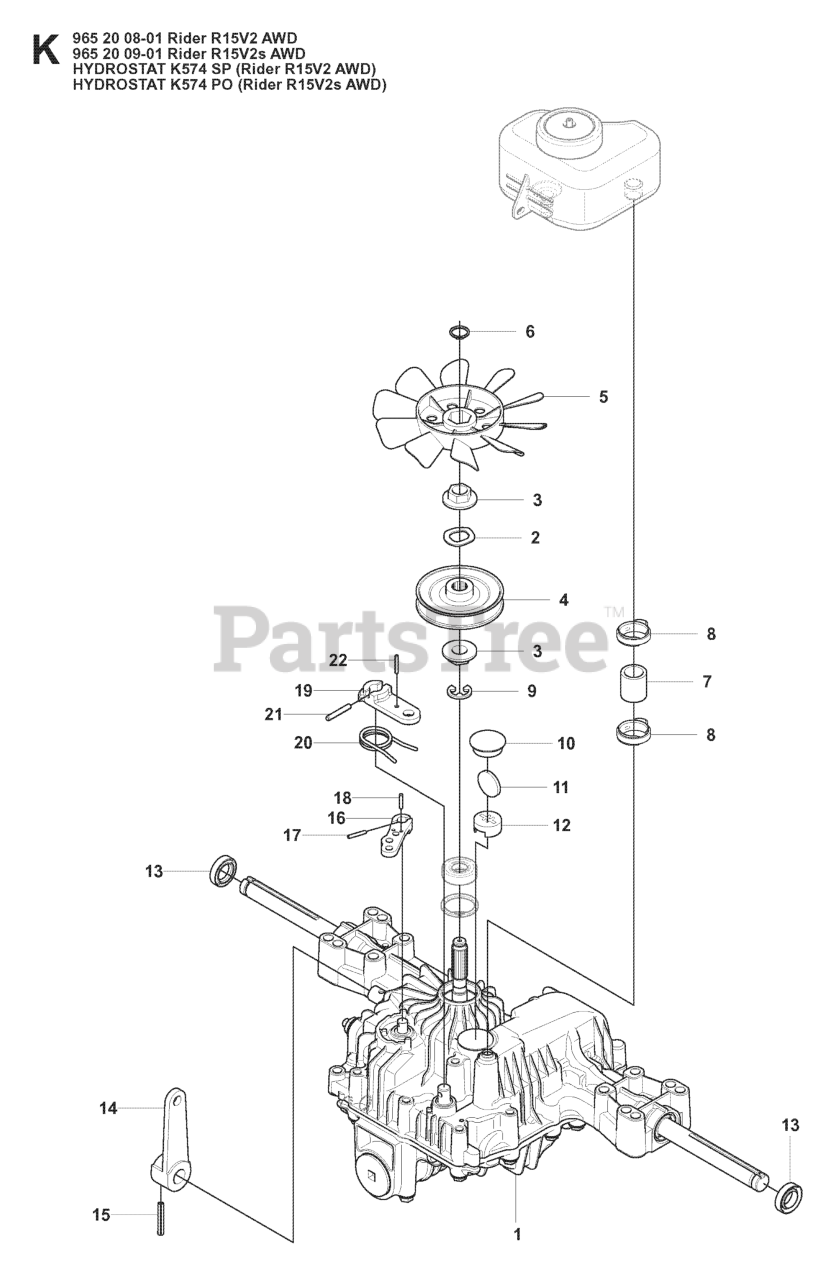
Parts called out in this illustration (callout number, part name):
1	HYDRAULMOTOR
4	PULLEY - 3 1/2"
5	FAN.BLACK.1A646083070
6	RETAINING RING **
7	PIPE
8	CLAMP
9	Retaining Ring
13	RP SEAL.19, 19216334280
20	RETURN SPRING
